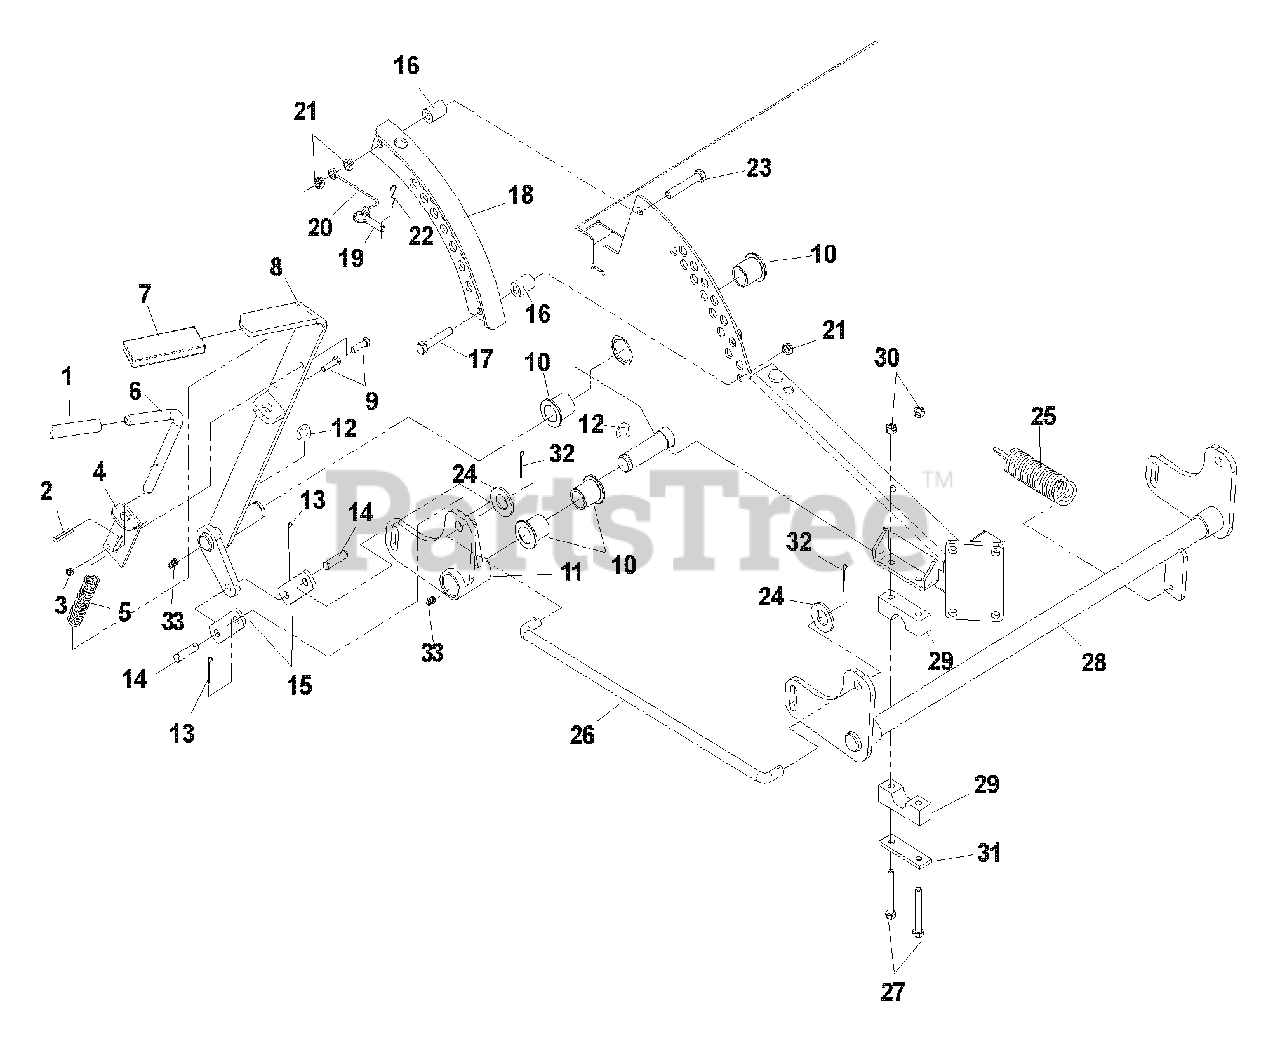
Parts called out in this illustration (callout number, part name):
2	GROOVED PIN
3	NUT1/4C CENTER LOCK
4	PIN MT, UPPER
8	LEVER WLDMT
9	HCS 1/4C X 3/4
10	FLANGED BUSHING
11	BELLCRANK WLDMT - RT
12	7/8 'E' RING
13	COTTER PIN, 1/8 X 3/4
14	CLEVIS PIN, 3/8 X 1 1/8
17	HCS 3/8C X 2
18	ADJUSTMENT PLATE
21	NUT 3/8C NYLOC
22	HAIRPIN, #4
23	HCS 3/8C X 2 1/2
24	BUSHING, 5/8 MACH.
26	DECK LIFT LINK
27	HCS 5/16C X 2 3/4
28	LIFT WLDMT
29	LIFT BLOCK
30	NUT 5/16C NYLOC
31	REINF. PLATE
32	COTTER PIN, 5/32 X 1 1/4
